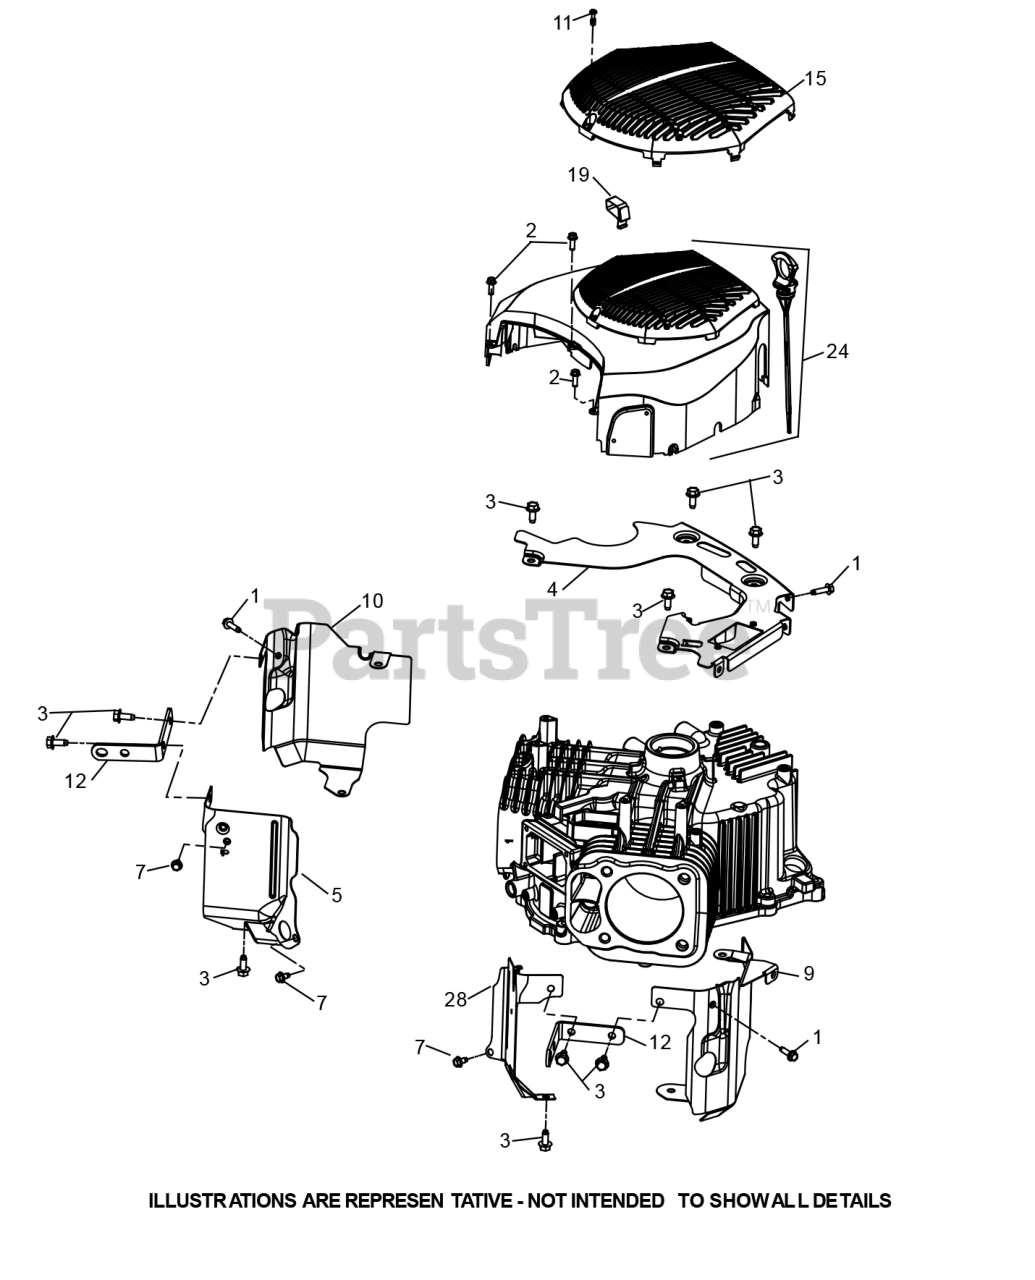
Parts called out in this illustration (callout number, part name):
1	THREAD FORMING SCREW
3	SCREW-THREAD FORMI
4	PLATE-BACKING
5	VALLEY BAFFLE-# 1
9	BAFFLE-LEFT BARREL
10	BAFFLE-RIGHT BARRE
11	SCREW- M5-2.42 (PT
12	STRAP-LIFTING
19	BLOWER HOUSING CLIP
24	BLOWER HOUSING KIT
28	VALLEY BAFFLE #2
